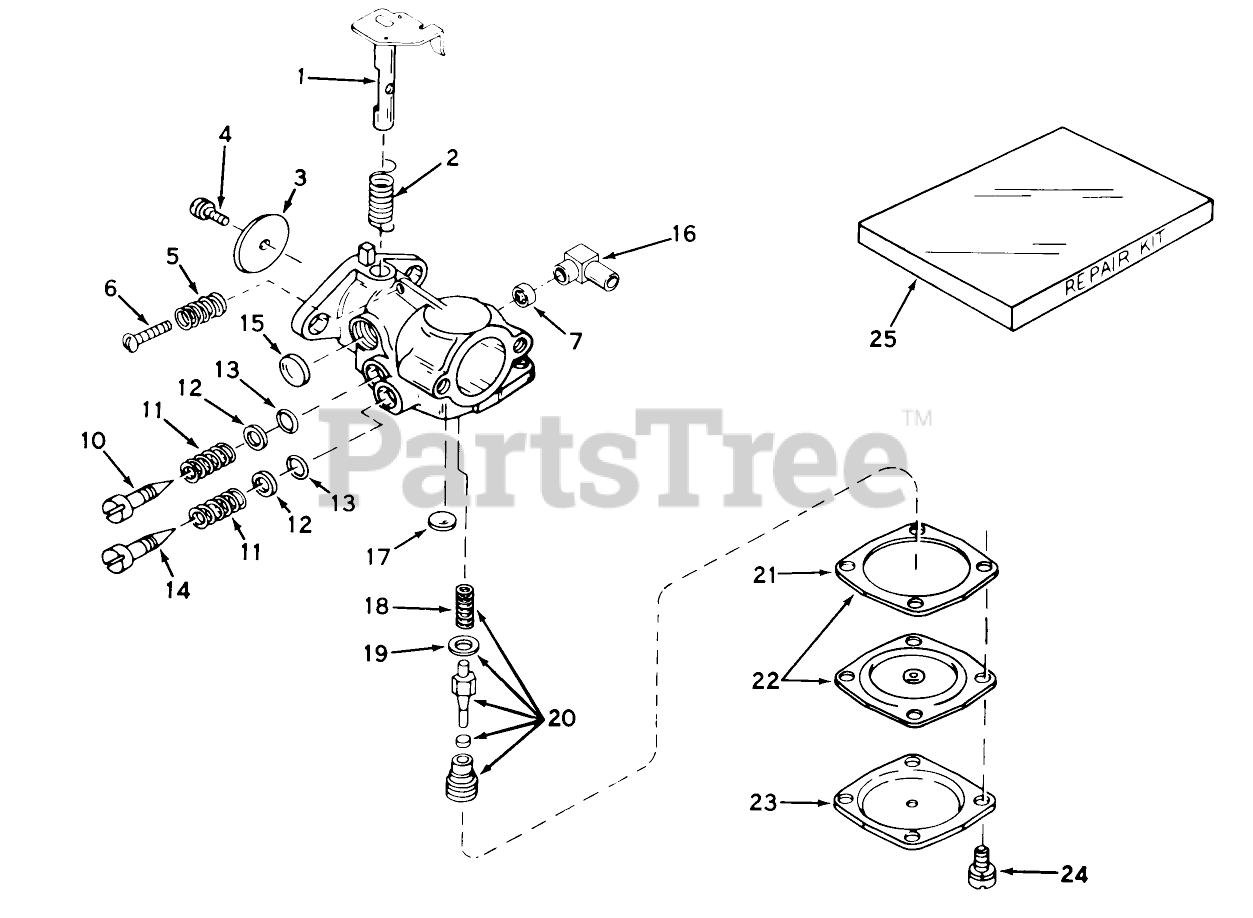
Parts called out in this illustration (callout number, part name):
1	Shaft Lever Assy.
2	Spring, Throtte Return
3	Shutter, Throttle
4	Screw-Shutter
5	Spring-Tension
6	Screw-Throttle Crack Screw / Idle Speed
7	Valve Check
10	Screw, Idle Adjustment
11	Spring
12	Washer
13	ORing
14	Screw, Main Adjustment
15	Plug-Welch, Idle Mixture Well
16	Nipple, Fuel Inlet
17	Plug Welch
18	Spring, Needle Valve
19	Gasket-Valve Seat
20	Needle, Valve, Seat Gasket
21	Gasket-Diaphragm
22	Diaphragm Ass. (Incl. No. 21)
23	63561/33165A O"HITC
24	Screw, Diaphragm Cover
25	Repair Kit
